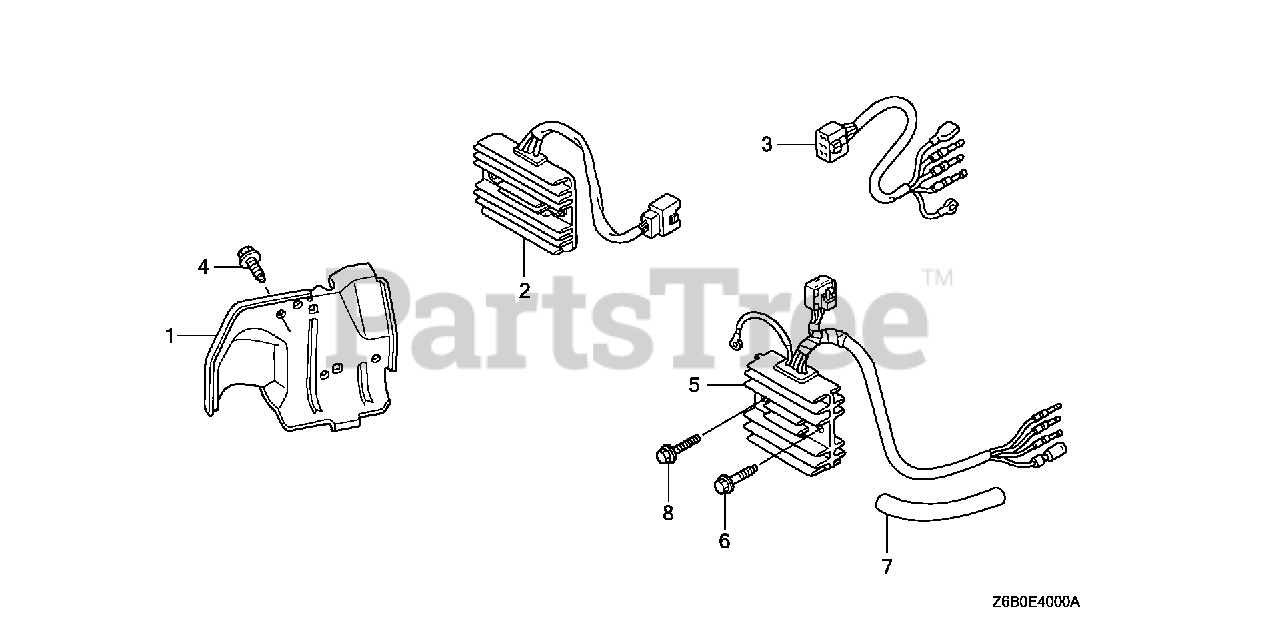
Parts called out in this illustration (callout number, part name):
5	RECTIFIER ASSY., REGULATOR
6	BOLT, FLANGE (6X25) (CT200)
7	TUBE, CORD
8	BOLT, FLANGE (6X25)
